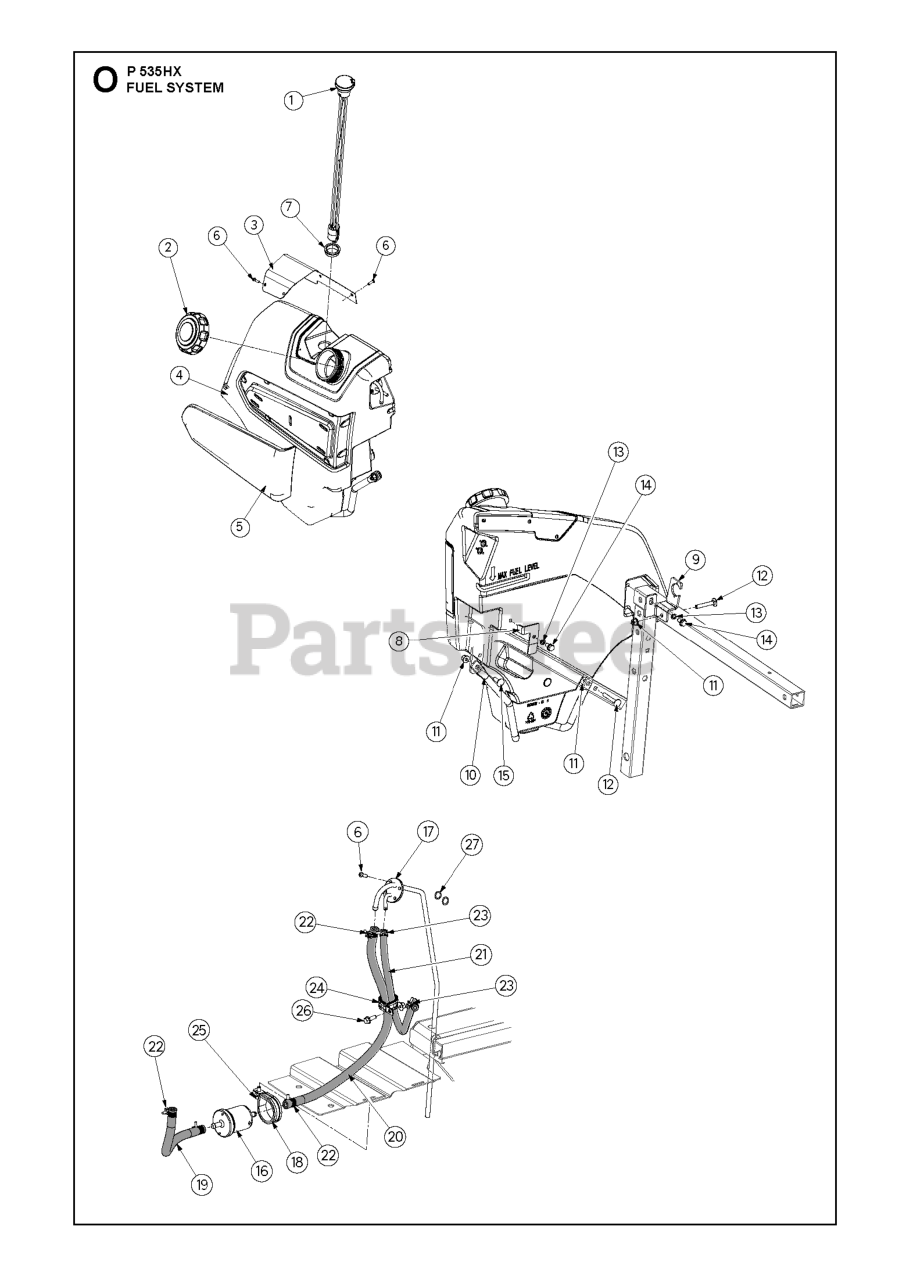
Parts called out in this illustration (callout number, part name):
6	SCREW ITXPANT T50X16 ZN/FE (A
7	GROMMET, FUEL SENSOR
11	NUT FLANGE
13	WASHER LOCK 8.7X13.5X2.5 ZN FL
22	RP HOSE CLAMP FUEL HOSE
23	HOSE CLAMP
24	HOSE CLAMP
25	SCREW EHHFM
